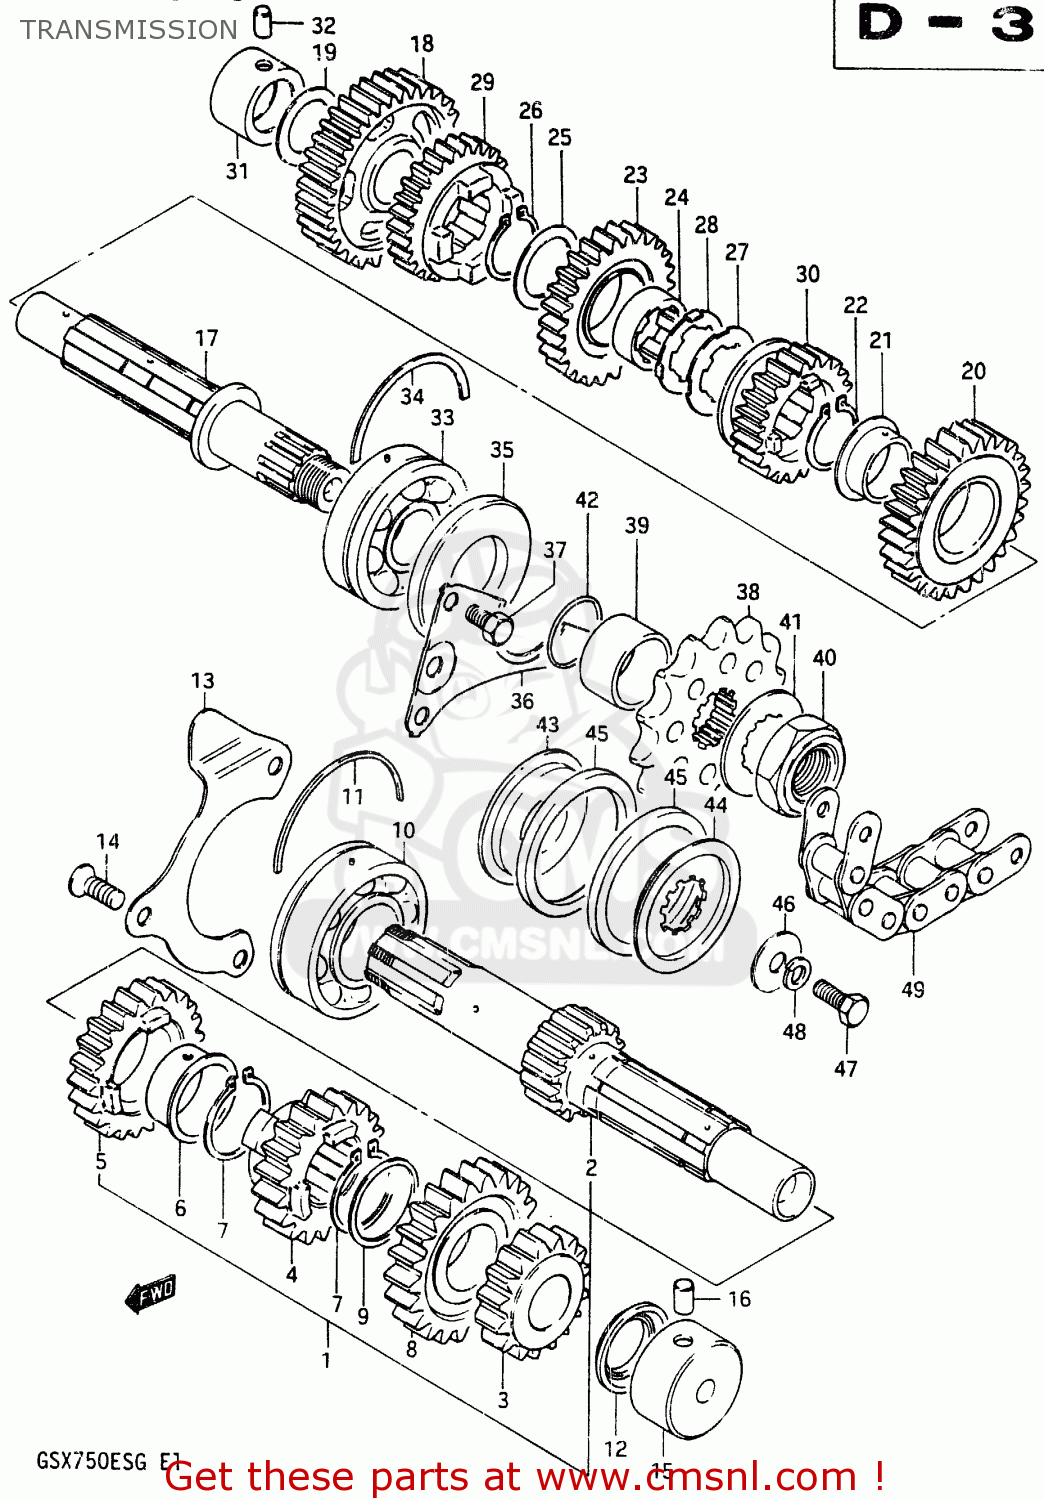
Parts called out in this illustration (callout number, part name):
1	SHAFT,COUNTER
2	SHAFT,COUNTER
3	GEAR,SECOND DRIVE
4	GEAR,THIRD DRIVE
5	GEAR,FOURTH DRIVE
6	BUSHING
7	RING,SNAP
8	GEAR,FIFTH DRIVE (NT:23)
9	WASHER,LOCK
10	BEARING(25X62X17)
11	C-RING
12	SEAL,OIL(20X31.2X2.7)
13	PLATE,COUNTERSHAFT BEARING
14	SCREW
15	BEARING(20X34X17.5)
16	PIN
17	SHAFT,DRIVE
18	GEAR,1ST DRIVEN(NT:35)
19	WASHER
20	GEAR,2ND DRIVEN(NT:28)
21	BUSH(28X32X2)
22	CIRCLIP
23	GEAR,THIRD DRIVEN
24	BUSH,3RD DRIVEN GEAR
25	WASHER,LOCK
26	CIRCLIP
27	WASHER,LOCK
28	WASHER
29	GEAR,4TH DRIVEN(NT:26)
30	GEAR,5TH DRIVEN(NT:22)
31	BEARING(20X34X20)
32	PIN
33	BALL BEARING 25X62X17
34	C-RING
35	SEAL,OIL(33X62X7)
36	PLATE,DRIVESHAFT OIL
37	BOLT
38	SPROCKET,ENGINE
39	SPACER
40	NUT
41	WASHER
42	O RING(D:1,ID:24.5)
43	HOLDER, SPROCKET, NO.1
44	HOLDER,SPROCKET DAMPER
45	DAMPER,SPROCKET
46	WASHER
47	BOLT, UPPER
48	LOCK WASHER
49	CHAIN ASSEMBLY,DRIVE
